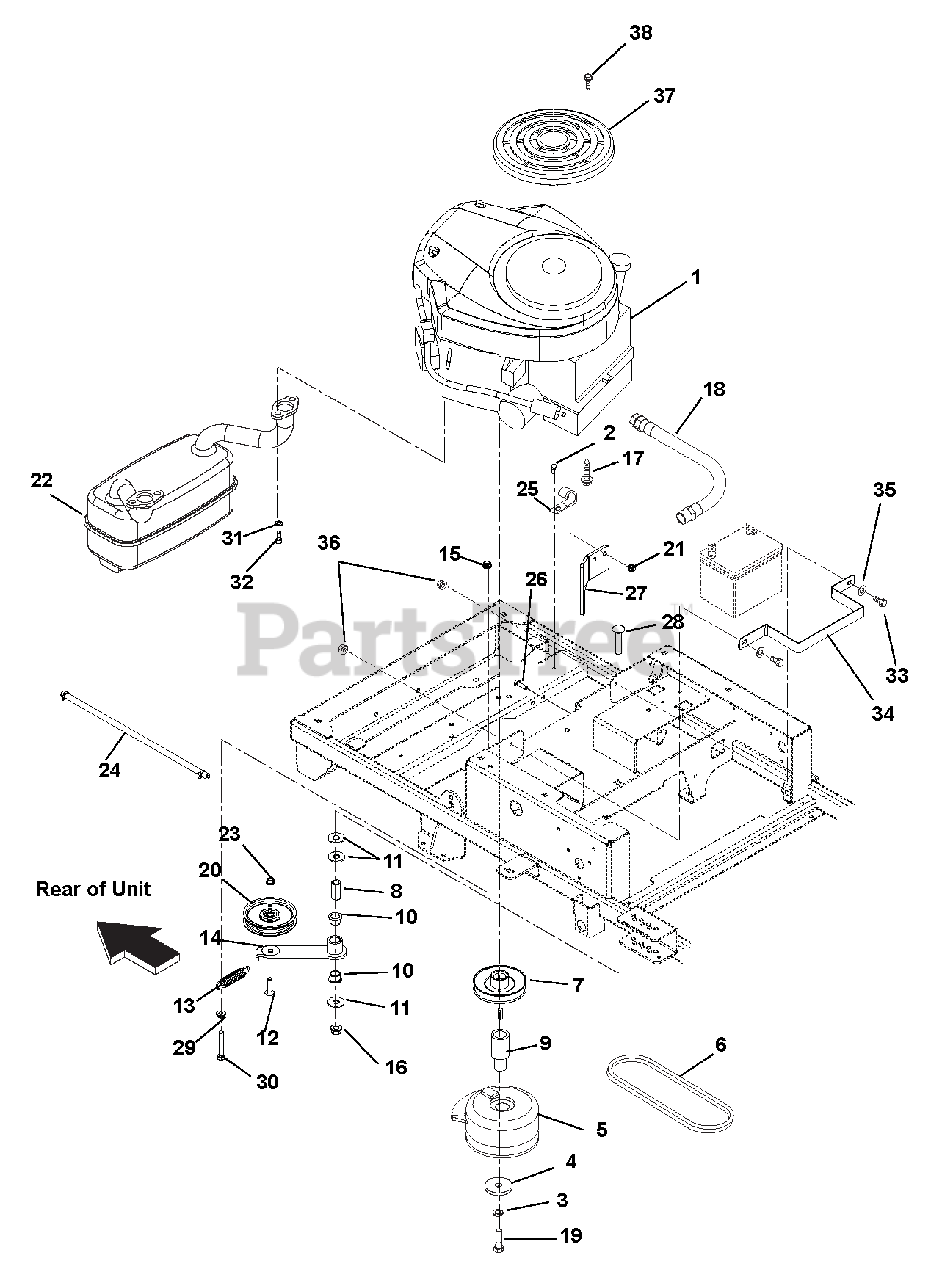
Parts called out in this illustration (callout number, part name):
1	ENGINE, 18HP V-TWIN CE
2	@SCR-TAP .25-20X.37 HWH YWZ TR
3	@WSHR-LK .44X.109 REG YWZC
4	WSHR-FL-STL .469X2.00X.25 YWZC
5	CLUTCH, MS WITH BRAKE
6	V-BELT, HA-WRAPPED
7	PLY-V 4.5X1.5 AB SECTION W/KEY
8	BSHG-SLV .500X.750X1.560
9	EXT-CRANKSHAFT LOWER
10	BSHG-FLG 0.75X0.875X.625X1.125
11	@WSHR-FL-STL.563X1.38X.109YWZC
12	@BLT-RDHDSQNK .38-16X1.50 G5YZ
13	SG-TENS .105X.812X3.88 WLD 15
14	WMT, GROUND DRIVE IDLER ARM
15	@NUT-LK-NYL-FLG .38-16 YWZC
16	@NUT-LK-TOP-FLG .50-13 YWZC
17	@SCR-TAP .38-16X1.00 HWH TR YZ
18	HOSE, HYD .38-11-0K M6N0-F6J0
19	BLT-HEX .44-20X4.50 GR8 YWZC
20	ASM, 4" IDLER (.75 WIDE)
21	@NUT-LK-NYL-FLG .31-18 YWZC
22	MUFFLER - TWIN BRIGGS
23	@NUT-LK-TOP-FLG .38-16 YWZC
24	ASM, FUEL HOSE
25	J-CLAMP
26	@BLT-HEX .31-18X1.00 GR5 YWZC
27	CLUTCH STOP
28	@BLT-RDHDSQNK .50-13X2.50 G5YZ
29	@NUT-SPNLK-FLG .375-16 YWZC
30	@BLT-HEX .38-16X2.50 GR5 YWZC
31	@WSHR-LK .31X.078 REG YWZC
32	SCR-CAP .31-18X.75 S/HD
33	@BLT-HEX .25-20X.75 GR5 YWZC
34	BRKT, BATTERY HOLD DOWN
35	@WSHR-FL-STL.281X.62X.065 YWZC
36	NUT-KEPS .250-20
37	GUARD, BRIGGS ENGINE
38	SCREW, 8-16X.87 PHPAN 3 LOBE
